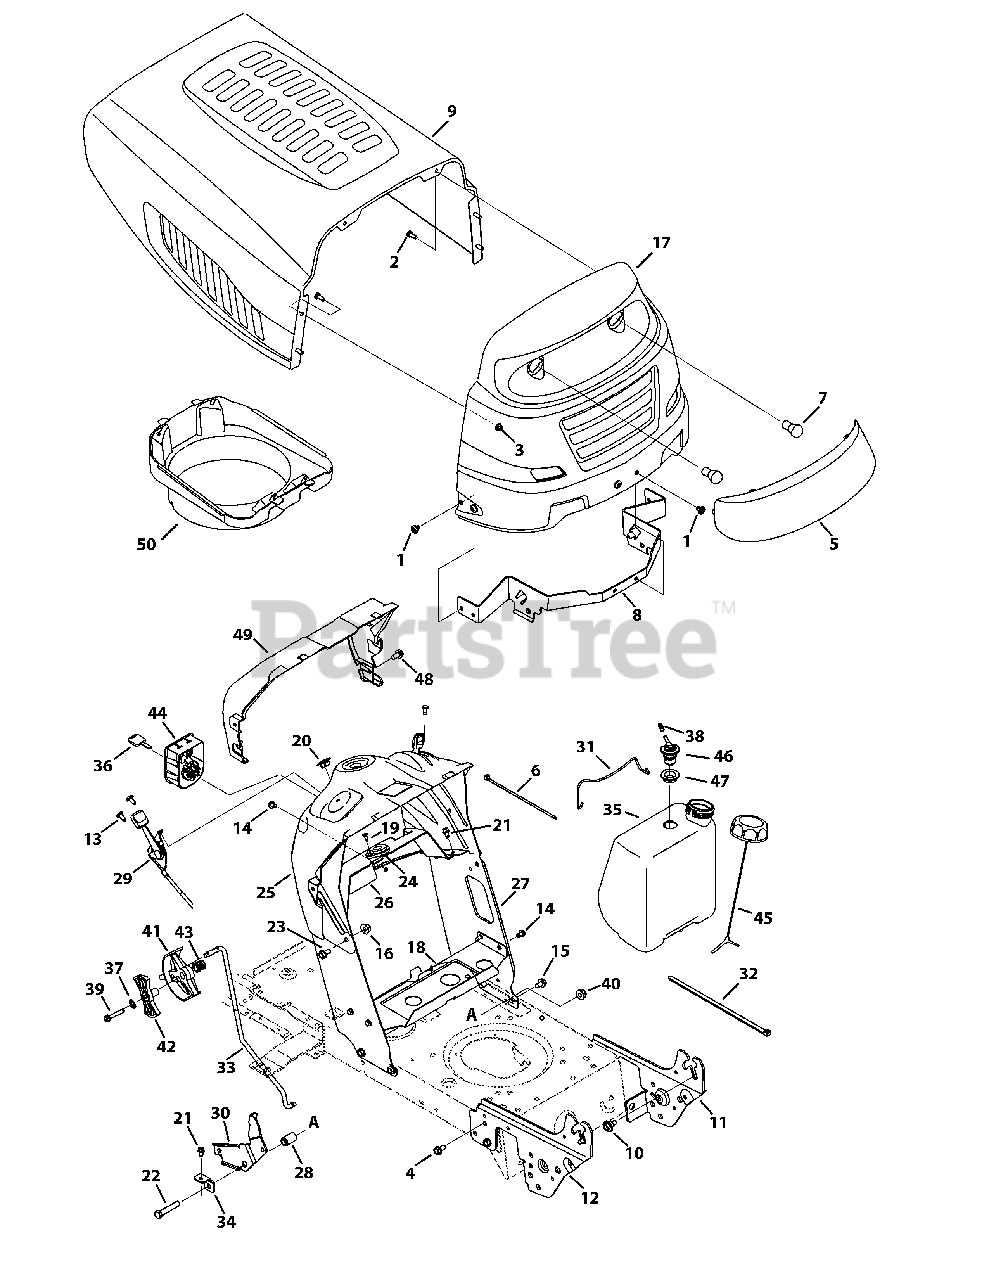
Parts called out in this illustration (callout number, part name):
1	Screw, 5/16-18 x .375
2	Hex Screw, 1/4-20 x .620
3	Flangelock Nut, 1/4-20
4	Screw, 5/16-18 x .750
5	Grill Lens
6	Cable Tie
8	Hood Pivot Bracket
10	Shoulder Screw, 5/16-18 x .43 x .29
11	Left Support Pivot Bracket
12	Right Support Pivot Bracket
13	Screw, 1/4-20 x .500
14	Screw, 1/4-20 x .500
15	Screw, 5/16-18 x .625
16	Flangelock Nut, 5/16-18
18	Gas Tank Support Bracket
19	Screw, #10-16 x .500
20	Choke Plug
21	Tap Screw, 1/4-20, 0.625
22	Hex Screw, 3/8-16 x 2.0
23	Hex Screw, 5/16-18 x .625
24	Bearing, .628 ID x 1.36
25	Dash, Upper No RMC
26	Bracket, Steering Support
27	Dash, Lower
28	Flange Spacer, .390 x .671 x 1.095
29	Throttle/Choke Cable
30	Speed Latch - No RMC
31	Battery Assembly Rod
32	Cable Tie
33	Speed Control Rod
34	Speed Latch Tab
35	1.36 Gallon Fuel Tank
36	Key, Assembly
37	Lock Washer, 1/4
38	Hose Vent, 3/16 EPA
39	Hex Washer Screw, 1/4-20 x 1.50
40	Flangelock Nut, 3/8-16
41	Shift Lever
42	Index Control
43	Compr. Spring, .72 OD x .78
44	3 Position Key Switch
45	Fuel Cap, 2.25"
46	Rollover Valve
47	Rubber Grommet, 23 x 3.55
48	Screw, 1/4-15 x .750
49	Dash Collar
